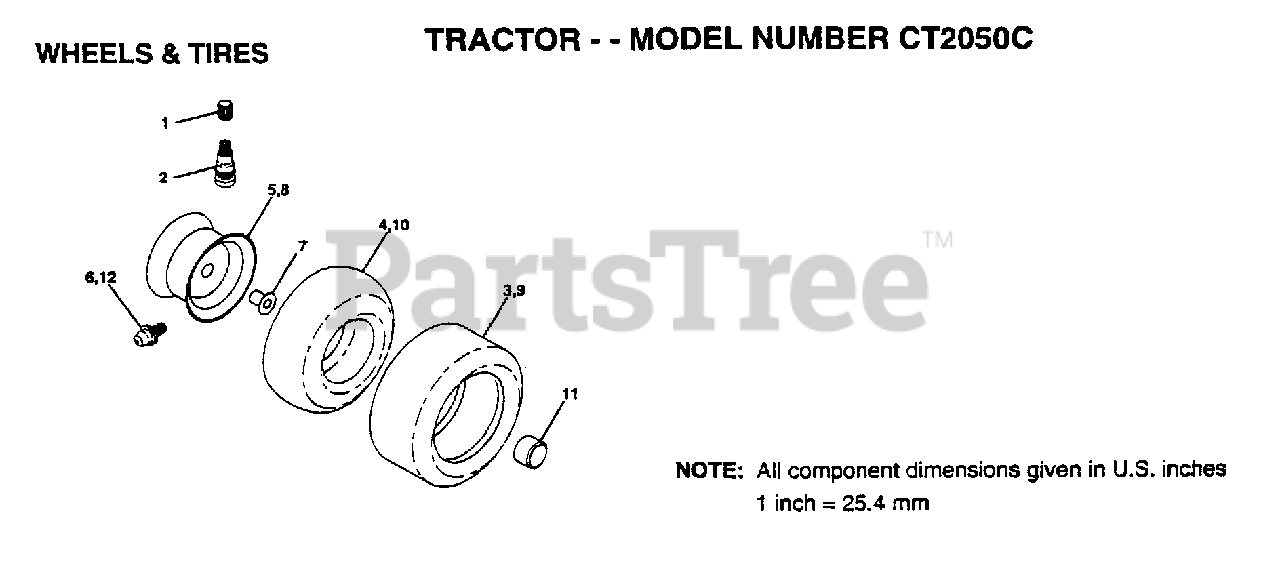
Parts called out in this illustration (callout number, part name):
1	VALVE CAP
2	VALVE STEM LT
4	TUBE.16X6.5/7.5-8
5	"RIM.FRONT.8"".YEL"
6	ZERK FITTING M
7	"FLANGE, BEARING"
8	"RIM.REAR.12"".YEL"
10	TUBE.23X8/10-12
11	HUB CAP
12	FITTING LT
